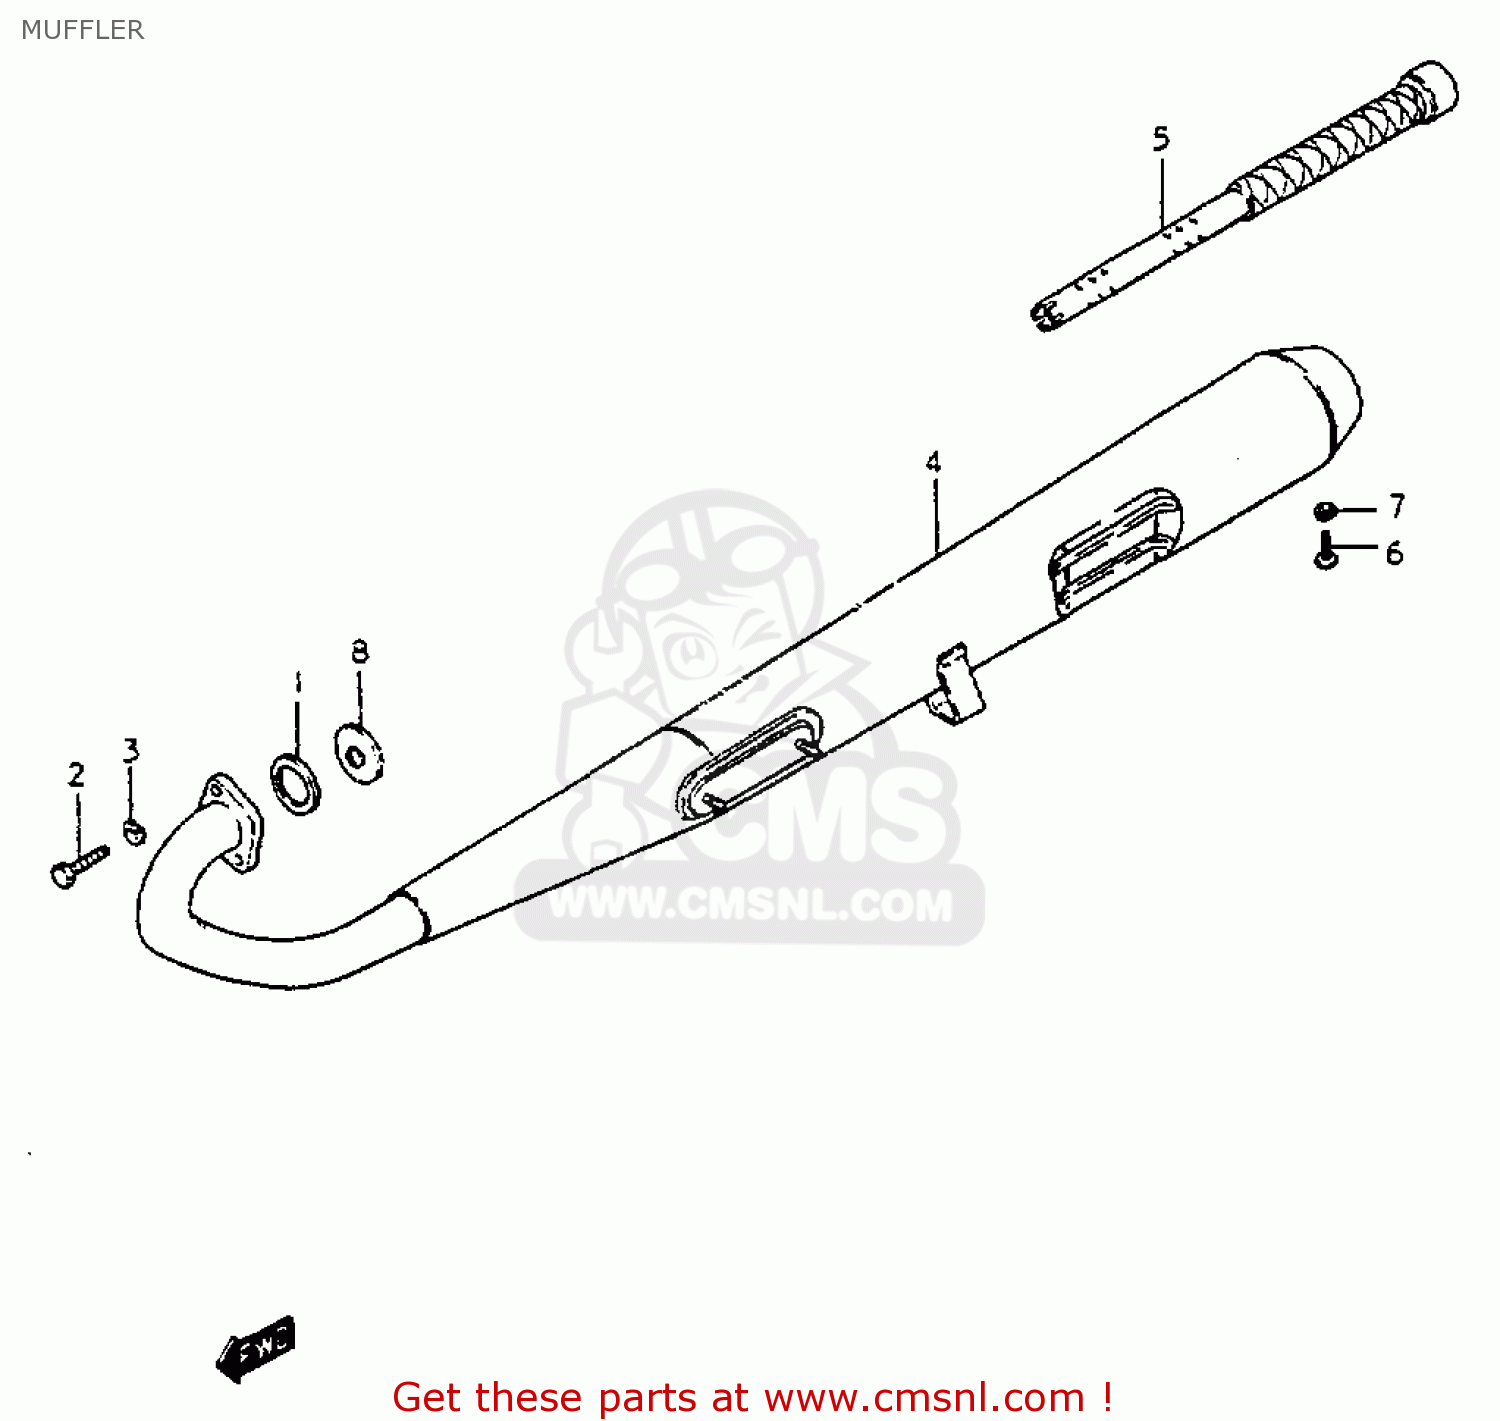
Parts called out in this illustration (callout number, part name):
1	GASKET, EXHAUST PIPE
2	BOLT
3	LOCK WASHER
4	MUFFLER ASSY
5	PIPE,BAFFLE
6	BOLT(5X8)
7	LOCK WASHER
